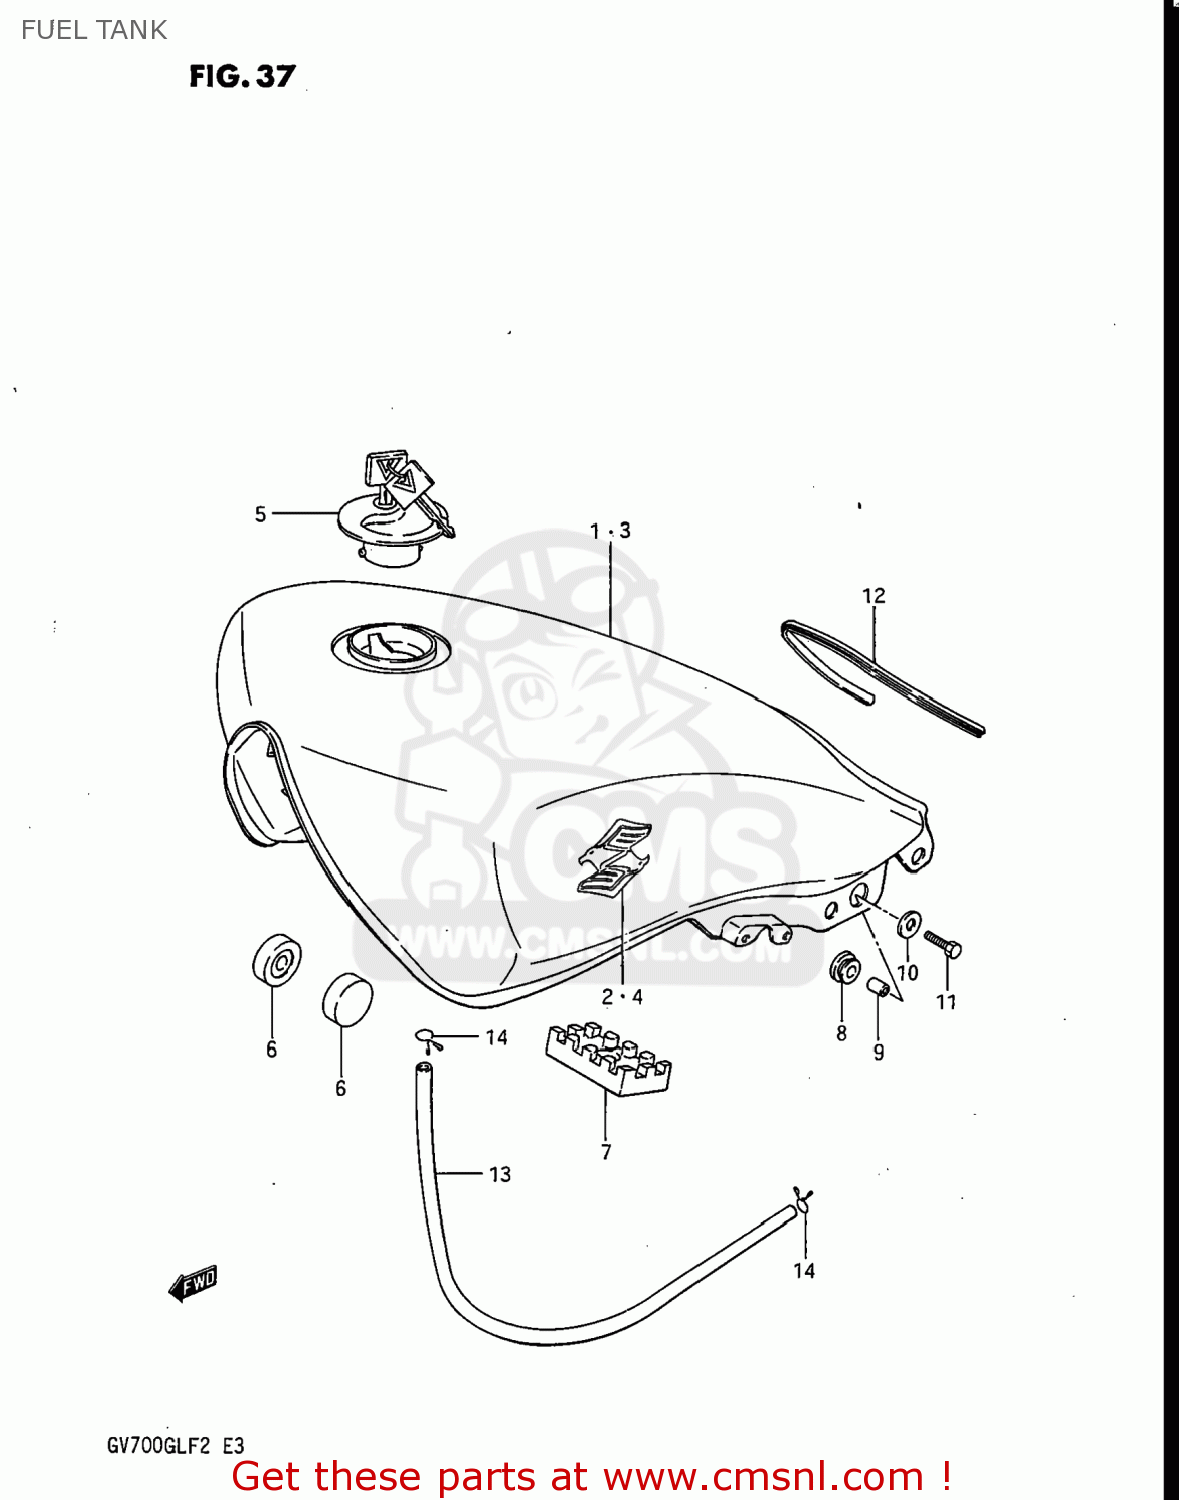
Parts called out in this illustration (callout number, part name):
1	TANK ASSEMBLY,FUEL
2	EMBLEM
3	TANK ASSEMBLY,FUEL
4	EMBLEM
5	CAP SET,FUEL TANK
6	CUSHION
7	CUSHION,FUEL TANK CTR
8	CUSHION
9	SPACER (6.8X10X10)
10	WASHER (6.5X24X1.6)
11	BOLT
13	HOSE
14	CLAMP
